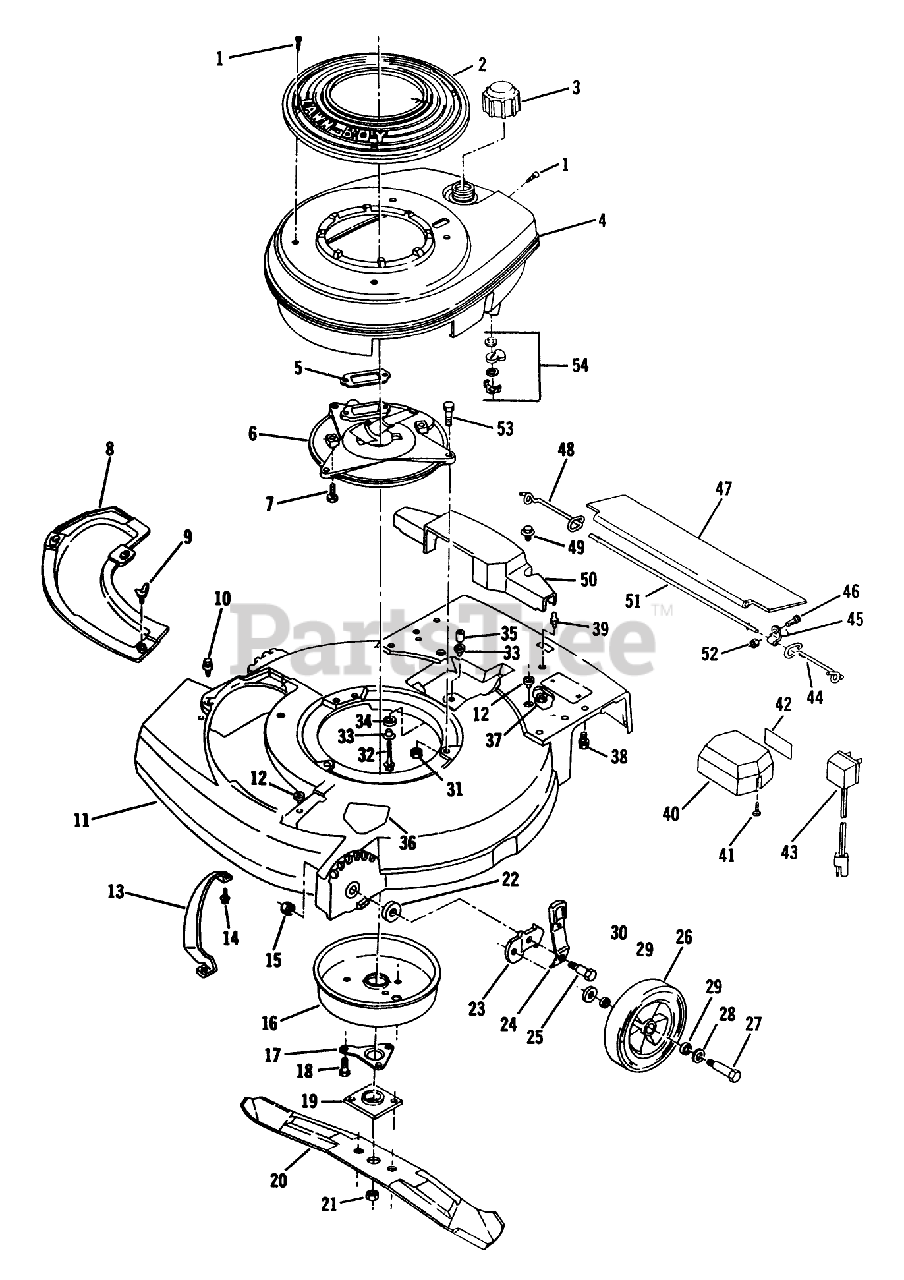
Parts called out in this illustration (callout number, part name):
1	SCREW - SELF TAPPING
3	FUEL CAP & INSERT
7	SCREW V
9	WING SCREW LAWRE
13	BAR-TOE
15	LOCKNUT
16	MUFFLER COVER F
17	SUPPORT F
19	PLATE AND COLLAR ASM
21	NUT-BLADE
26	WHEEL & TIRE KIT
27	BOLT WHEEL
30	WASHER WROUGHT
31	NUT-LOCK F
33	SPACER ECK PRES
34	GROMMET
44	SPRIG T/SHLD ASOC
45	CLAMP ROD KMC
48	SPRING;TRAILING SHIELD RH
49	SCREW SEMS TRM HEX HD
51	ROD 21" ADVANCE
52	LOCKNUT E
54	SHUT OFF VALVE KIT
